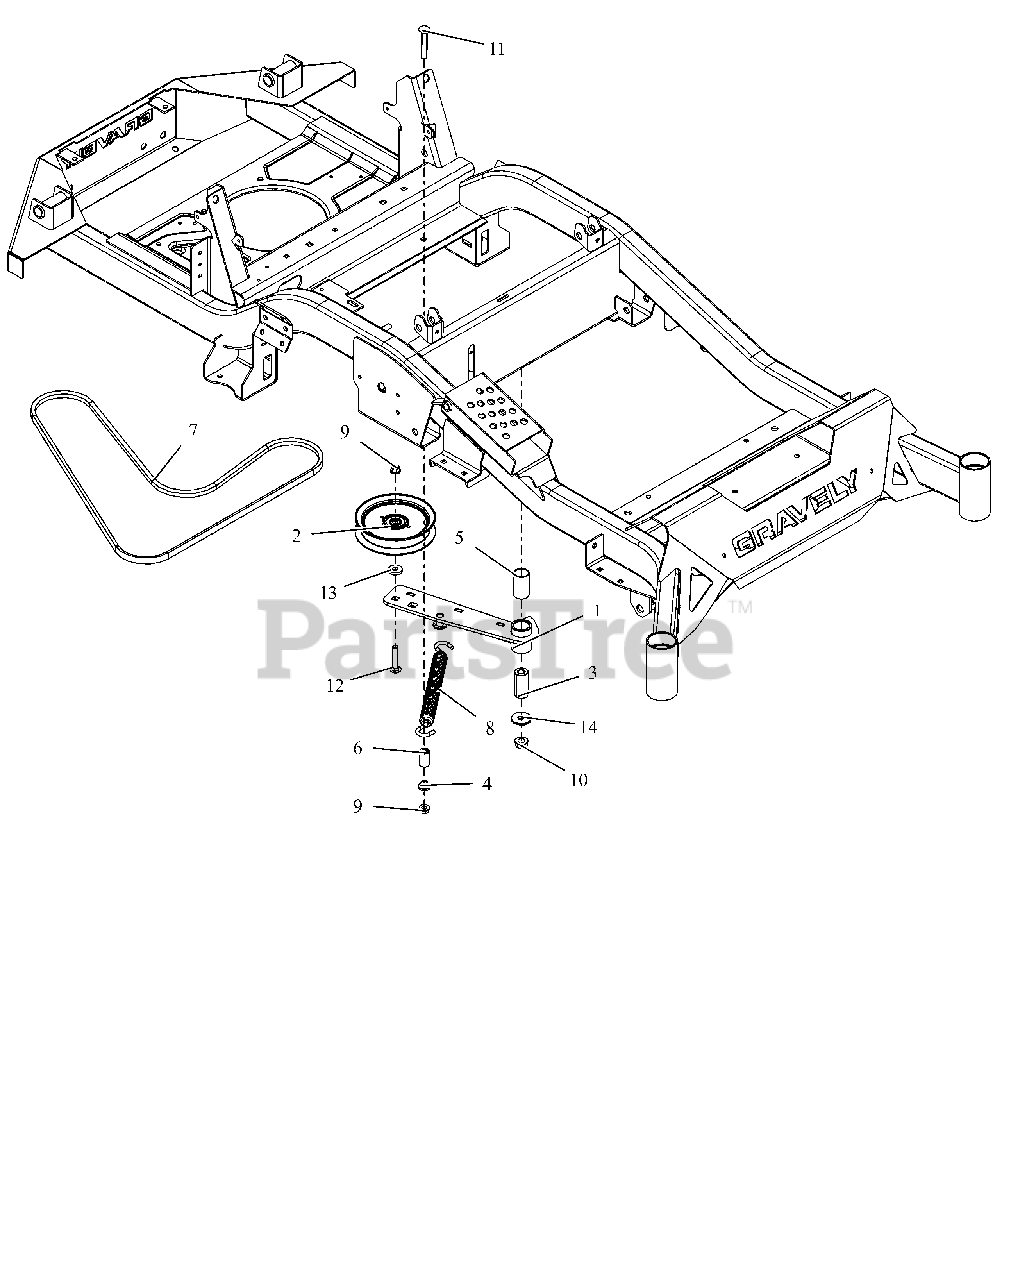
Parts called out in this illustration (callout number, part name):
1	WLDMT, HYDRO DRIVE IDLER ARM
2	IDLER, FLAT 5.00"
3	BSHG, SPCR .502X.997X2.03 PM
4	BSHG-FLG .385X.500X.875X.406
5	BSHG, 1.00X1.125X1.937
6	BUSHING, SLV .380X.750X1.190
7	V-BELT, 4L-WRAPPED
8	SPRING, EXTENSION
9	NUT-LK-TOP-FLG .38-16 ZC120
10	NUT-LK-TOP-FLG .500-13 GF ZCC
11	BLT, RHSSN.38-16X2.50 G5 ZCC
12	BLT, RHSN .38-16X2.00 G5 ZCC
13	WSHR, FLT .406X1.00X.188 ZCC
14	WSHR-FL-STL.511X1.44X.125ZC120
